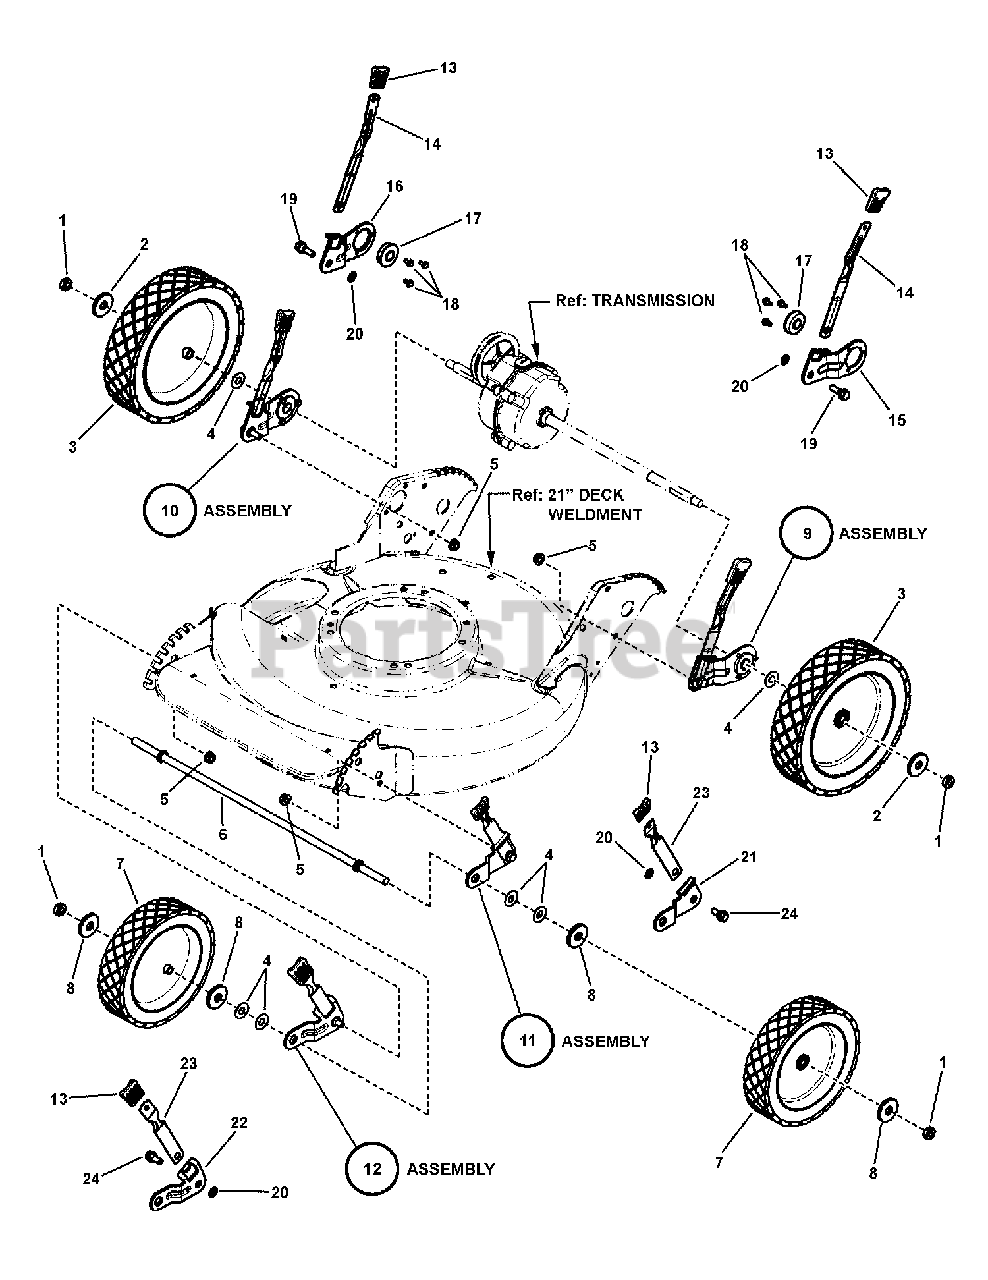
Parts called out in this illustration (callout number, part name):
1	NUT, 7/16-20 Hex Center lock Jam, GR 5, YZ
2	HUBCAP
3	WHEEL, 10 x 1.75- Steel-D- (Self Propelled)- Gray
4	WASHER, 7/16" Flat
5	NUT, 5/16-18 Hex Flange Lock, GR 5
6	AXLE, V21
7	WHEEL, 8 x 1.75- Steel - D- Gray
8	HUBCAP, V21
9	ASSEMBLY, Wheel Arm, Left Rear, Long
10	ASSEMBLY, Wheel Arm, Right Rear, Long
11	ASSEMBLY, Front Wheel Arm, LH
12	ASSEMBLY, Front Wheel Arm, RH
13	GRIP, Height Latch
14	LATCH, Height Adjusting, (long)
15	ARM, Wheel, Left Rear
16	ARM, Wheel, Right Rear
17	BEARING, 9/16" ID
18	SCREW, #10-32 x 3/8" Hex Washer Self-Tap, BZ
19	BOLT, 5/16-18 x 1" Hex Washer Face Shoulder
20	RETAINER, 5/16" Bolt
21	WHEEL ARM, L.H. Front (Square Hole)
22	WHEEL ARM, R.H. Front (Round Hole)
23	LATCH, Height
24	BOLT, 5/16-18 x 3/4" Hex Washer Face Shoulder
